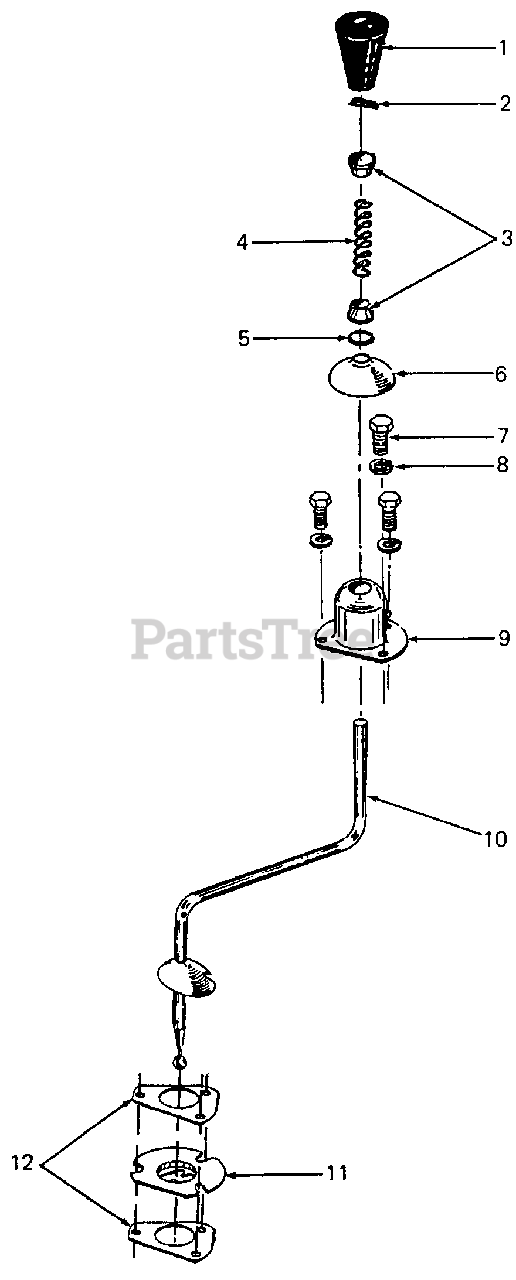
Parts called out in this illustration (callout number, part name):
1	Knob, Shift
2	Pin, Gear Shift Swivel Retainer
3	Retainer, Gear Shift Swivel Spring
4	Spring, Swivel
6	Shield, Gear Shift Lever
7	Screw, Hex Cap, 1/4-20 X .62 Lg GR5
8	Washer, Lock, 1/4
9	Housing Assy, Bell
10	Lever Assy, Shift
11	Guide, Shift
12	Gasket, Bell Housing
